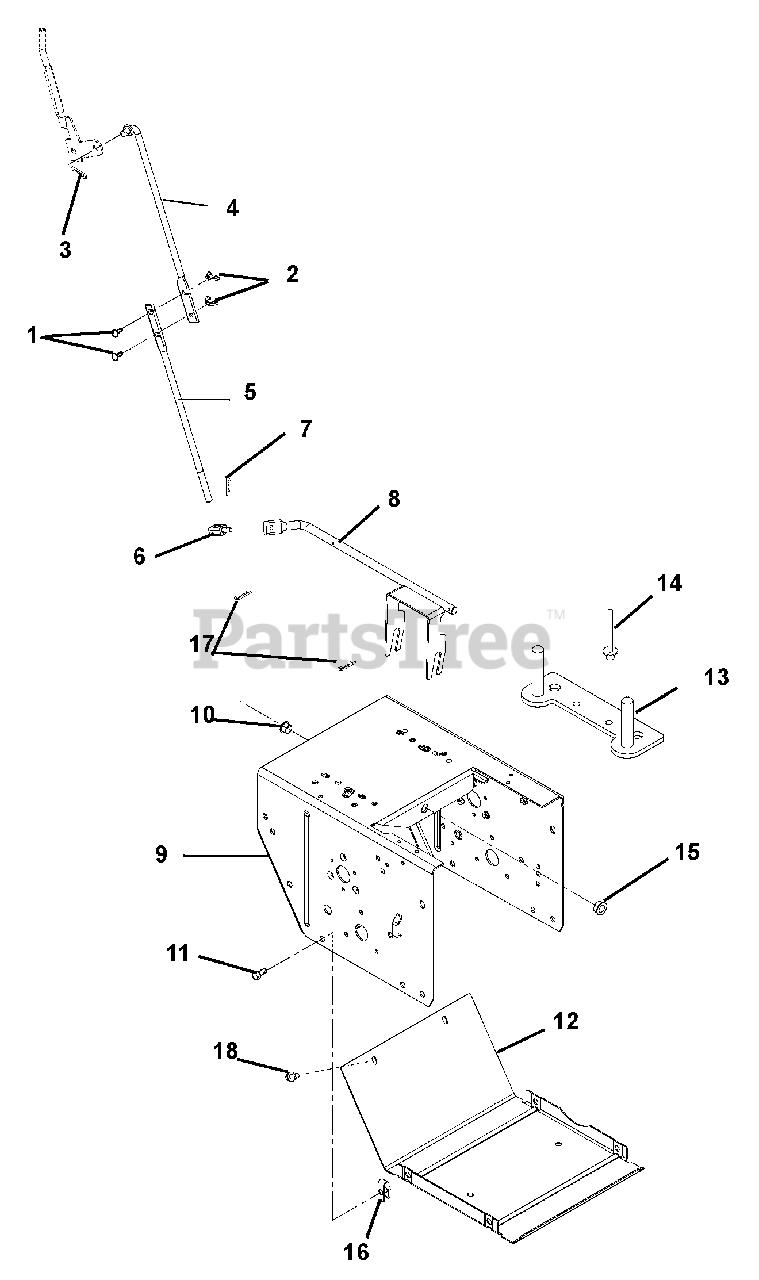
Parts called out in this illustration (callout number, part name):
1	@BLT-RDHDSQNK .25-20X1.00 G5YZ
2	NUT-LK WING .250-20 YWZC
3	PIN-HAIR, ENDRIES #25 YWZC
4	ROD, SHIFT-UPPER
5	ROD, SHIFT-LOWER
6	PIVOT,SHIFT ROD .375-16(TRUNN)
7	PIN-HAIR, ENDRIES #25 YWZC
8	ARM, SHIFT-WELDMENT
9	FRAME, MAIN
10	BUSHING, POLYLINER-.50 SPLIT
11	@SCR-MCH .25-20X.75 HWH YWZC
12	COVER, BOTTOM
13	STRAP, ENGINE BOLT-WELDMENT
14	RVT-POP .187X.45 DOME ALUM
15	BUSHING, POLYLINER-.50 SNAPIN
16	NUT-RTNR .25-20X.56
17	CLIP, SPRING
18	@SCR-TAP .25-20X.50 HWH TR YWZ
